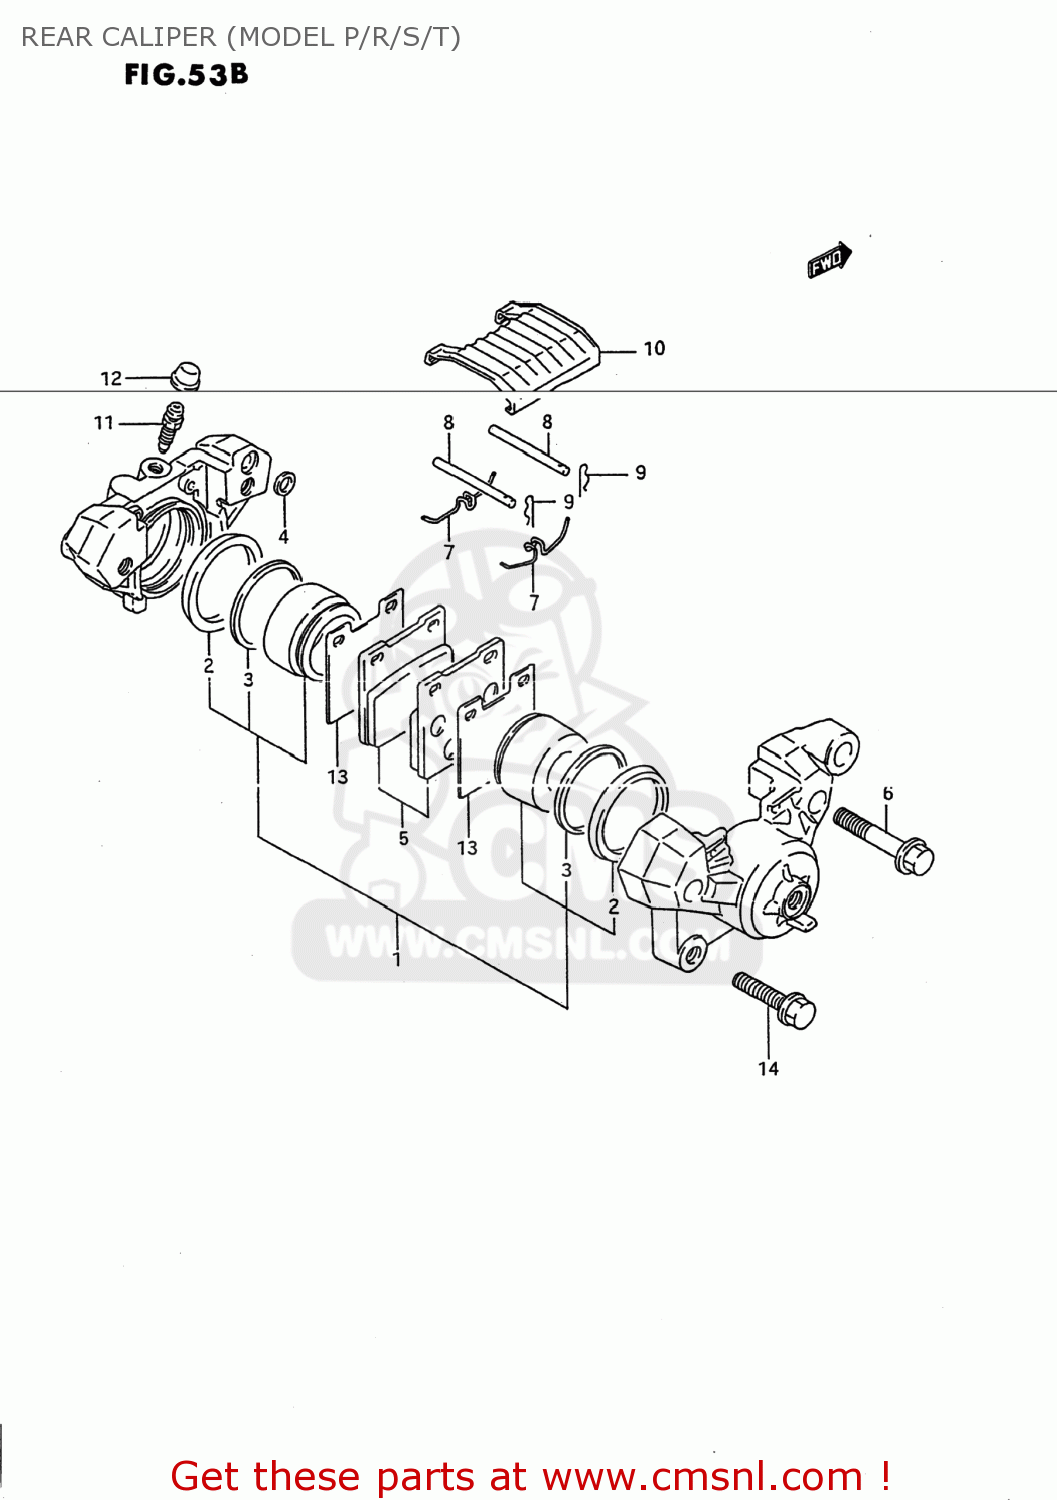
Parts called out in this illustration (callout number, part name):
1	PISTON SET
2	SEAL,PISTON
3	SEAL,WIPER
4	SEAL,JOINT
5	PAD SET (NAS)
6	BOLT
7	SPRING
8	PIN,PAD
9	CLIP,PAD PIN
10	COVER
11	BLEEDER
12	CAP,BLEEDER PLUG
13	SHIM,PAD
14	BOLT
